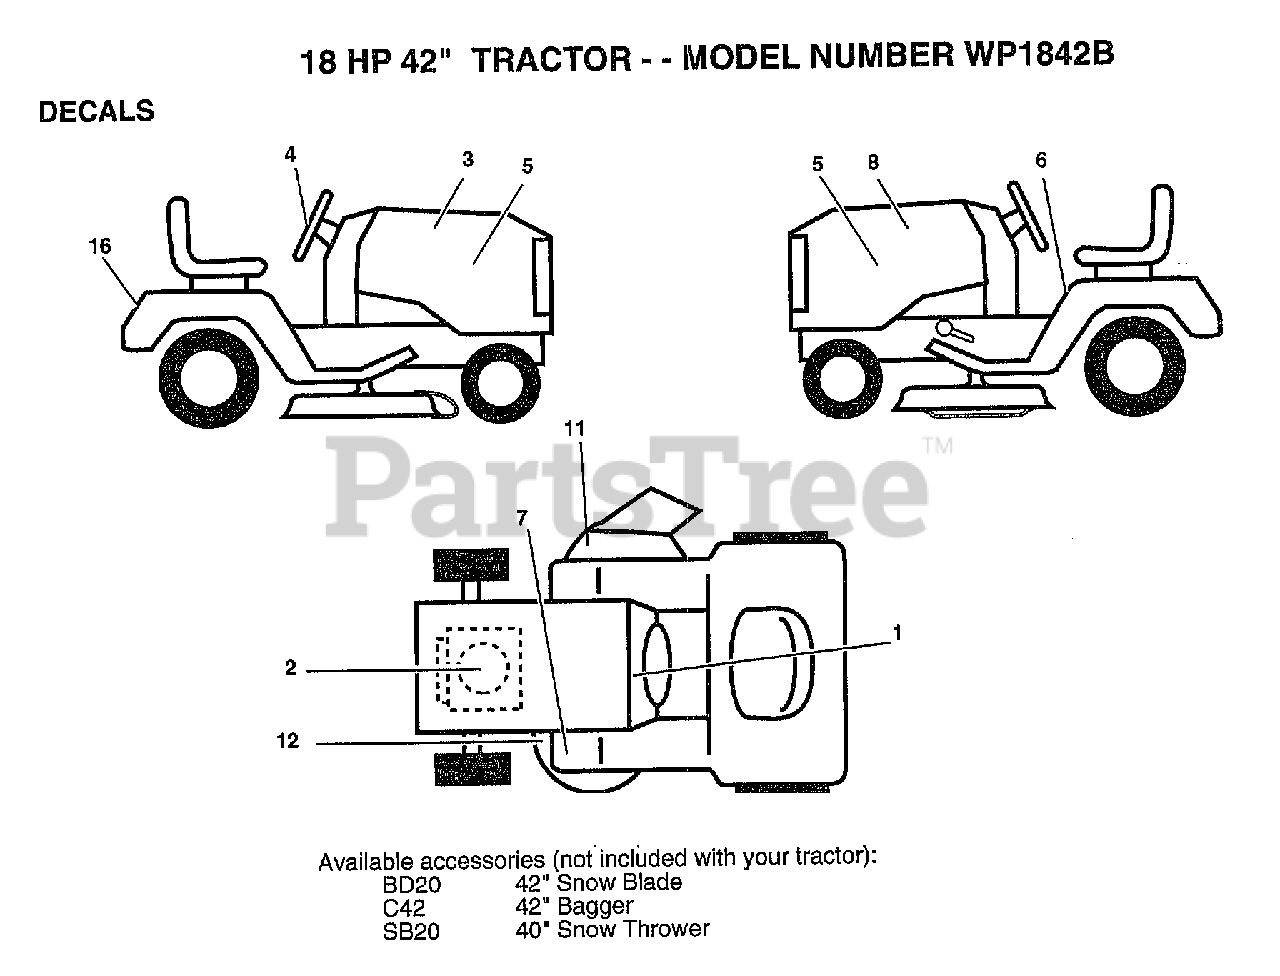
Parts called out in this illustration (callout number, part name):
1	DECAL.DASH.INST.
2	DECAL.ENG.272559
3	DECAL.HOOD.RH
4	DECAL, INSERT
5	DECAL, MODEL HOOD
6	DECAL
8	DECAL.HOOD.LH
12	DECAL
16	DECAL, LOGO, FENDER
